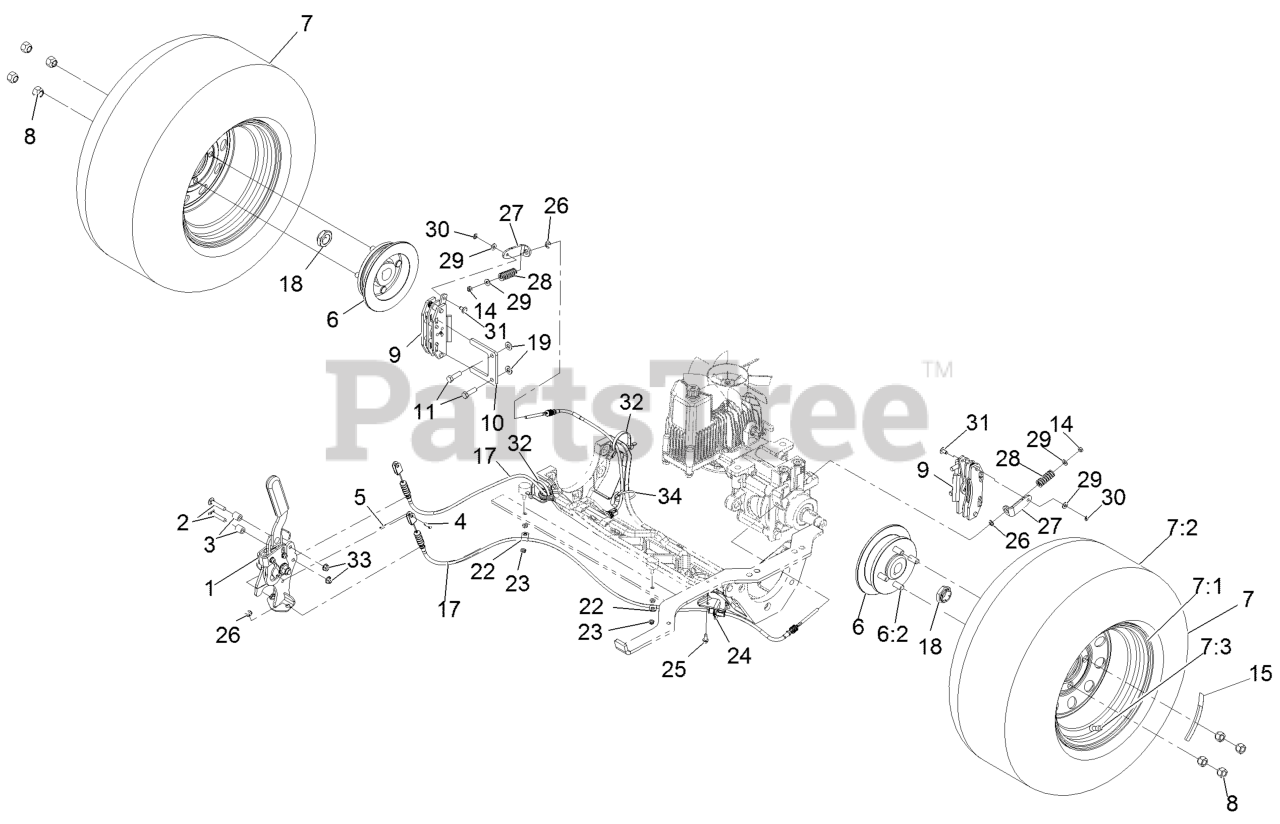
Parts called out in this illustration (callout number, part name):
1	BRAKE HANDLE ASM
2	SCREW-CARR
4	PIN-CLEVIS
5	PIN-COTTER
6	WHEEL HUB ASM
6:2	STUD-WHEEL
7	ASM-WHEEL AND TIRE
7:1	ASM-RIM 60
7:2	TIRE-DRIVE
7:3	Stem-Valve
8	NUT-LUG
9	CALIPER-BRAKE
10	PLATE-MOUNT, BRAKE
11	SCREW-LOCK, PATCH
14	NUT-LOCK, NI
15	DECAL-TORQUE, WHEEL HUB LUG
17	CABLE-BRAKE
18	LOCKNUT
19	WASHER-FLAT
23	NUT-LOCK, NI
24	BRACKET-CABLE
25	SCREW-HWH
27	BRACKET-BRAKE, L
28	SPRING-DIE
29	WASHER-FLAT
31	PIN-BRAKE
32	TIE-CABLE
33	NUT-HF, NI
34	TIE-CABLE
